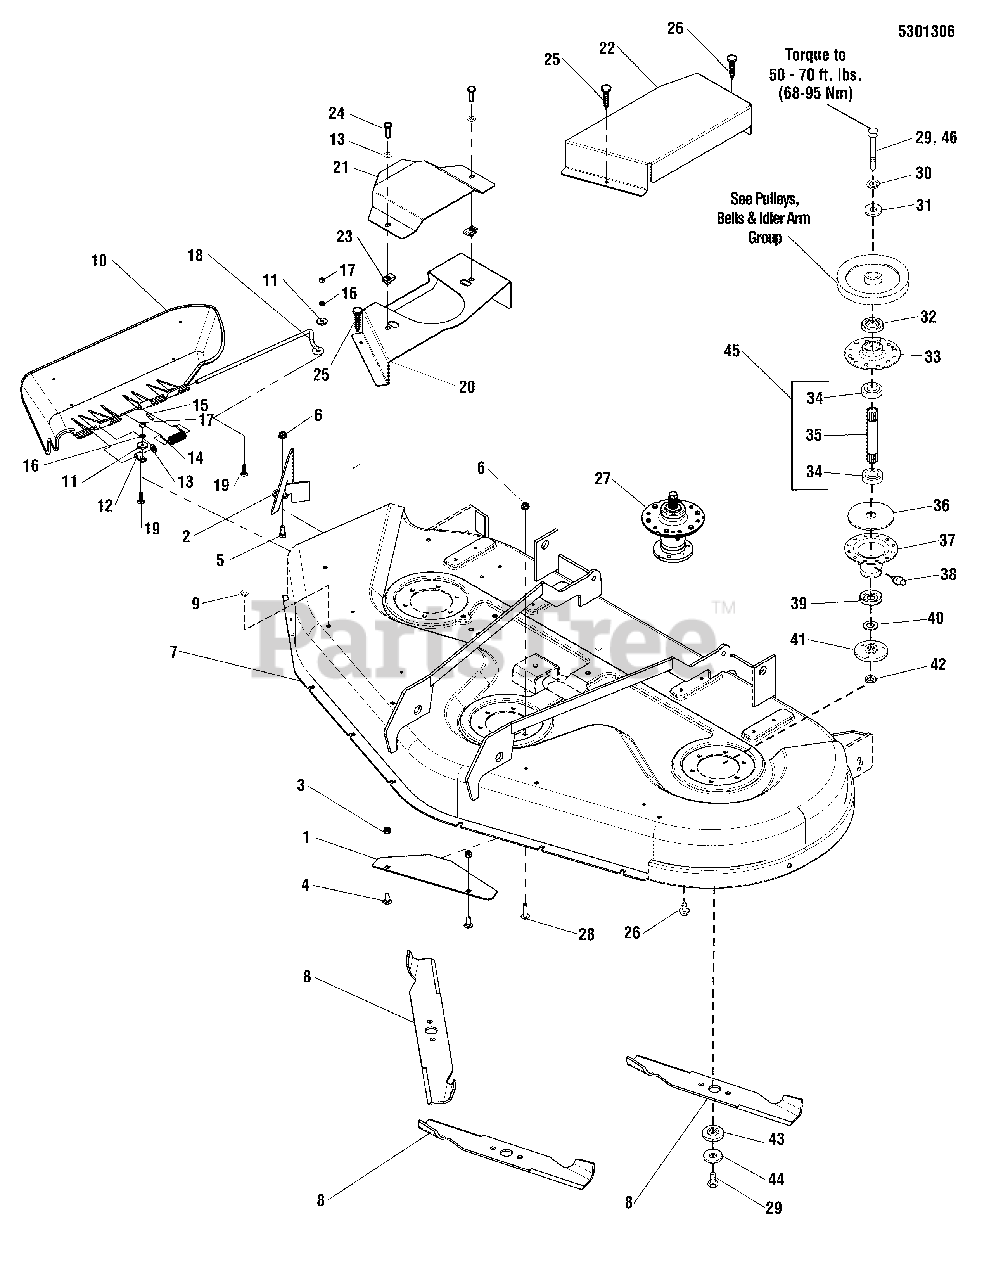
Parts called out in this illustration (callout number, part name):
1	BAFFLE, FRONT BLO-BLACK
2	BAFFLE, DISCHARGE 10GA 54" MWR-BLACK
3	NUT, 5/16-18 HEX NYLOCK FLANGE
4	BOLT, RD HD SH SQ NK 5/16-18X0.750 G5 BLK
5	BOLT, 5/16-18 X 3/4 GD5
6	NUT, 5/16-18 HEX NYLON LOCK
7	DECK SHELL W/DECALS, 52", SNP2654
8	KIT, 54" MOWER BLADES (1736043 - 2; 1736044 - 1)
9	PLUG, BUTTON FOR 0.344SQ HOLE BLACK POLY
10	DEFLECTOR, BLACK
11	WASHER, 0.250(0.26IDX0.84ODX.12THK) BLK
12	CLAMP, WIRE, .312DIA . (1) .281 HOLE BLK
13	WASHER, 0.312 (0.34IDX0.75ODX.06THK) BLK
14	SPRING, TORSION CHUTE 44/50" BLK
15	CAP, VINYL
16	LOCKWASHER, SPRING .250 BLK
17	NUT, 1/4-20 HEX
18	ROD, DEFLECTOR
19	BOLT, RD HD SH SQ NK 1/4-20X0.875 G5 BLK
20	PLATE, GUARD, MOWER DECK, 54", RH - RED
21	PLATE, GUARD, BLOWER PULLEY - RED
22	PLATE, GUARD, MOWER DECK, 54", LH - RED
23	BODY CLIP, 5/16-18 X 1/2 DEEP
24	BOLT, 5/16-18 X 3/4 GD5
25	CAPSCREW, Hex Washer Head Taptite, 1/4-20X0.375 .56
26	CAPSCREW, Hex Washer Head Taptite, 5/16-18X0.750BLK
27	SPINDLE ASSM, - STAMP STEEL LG SHAFT
28	BOLT, 5/16-18 X 1 1/4 FLANGE
29	CAPSCREW, HEX HEAD 7/16-14x1-1/4 G8 YELLO (SV)
30	LOCKWSHER, SPRING .438 BLK (SV)
31	WASHER, 0.438(0.45IDX1.25ODX.25THK) BLK (SV)
32	SHIELD, BEARING,MOWER ARBOR UPPER HT TR (SV)
33	HOUSING, ARBOR TOP - BLACK (SV)
34	BEARING, BALL 0.750ID 1.780OD 0.610LG (SV)
35	SHAFT, ARBOR 1.000DIA (SV)
36	GASKET, FOAM POLY (SV)
37	HOUSING & FITTING ASMY-LOWER BLACK (SV)
38	FITTING, LUBE .250 DRIVE .25SH BL CHK YEL (SV)
39	SHIELD, BEARING, MOWER ARBOR LOWER HT TR (SV)
40	WASHER, SHIM, .75 0.7535IDX1.388ODX0.30T (SV)
41	ADAPTER, BLADE 3.375OD INT SPLINE PWD MTL (SV)
42	RETAINING RING, EXT, #75 0.750 SELF LOCK (SV)
43	WASHER, Spacer, SPLN.6134IDX2.00OD.390TH SINTERPS (SV)
44	WASHER, Splined, 2" OD, .187" Thick (SV)
45	SHAFT & BEARING ASSM. (SV)
46	BOLT, HEX, 7/16-14X2-1/4, GD 5, YZ
